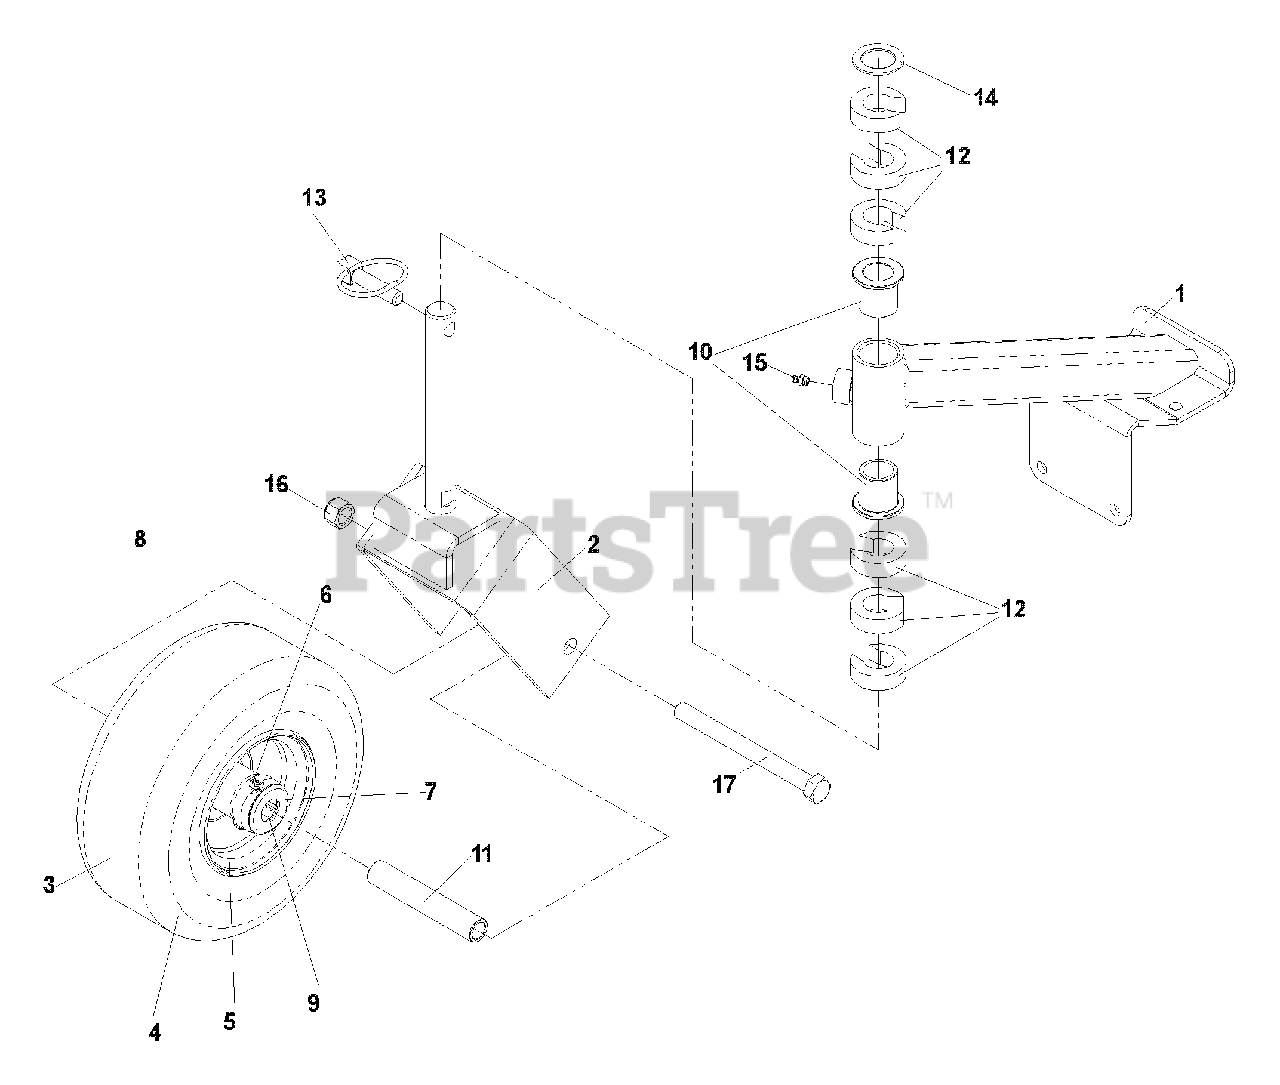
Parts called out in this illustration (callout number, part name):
1	CASTER ARM W/BUSHINGS
2	CASTER FORK
3	WHEEL ASSEMBLY
7	ENDCAP
8	NOTCHED ENDCAP
9	ROLLER BEARING
10	BUSHING, FLANGED
12	"C" SPACER
13	LYNCH PIN, 7/16
14	MACHINERY BUSHING, 1" X 14 GA
15	ZERK
16	NUT, 1/2C, NYLOC
17	HCS, 1/2-13 X 5 1/2, GR5
